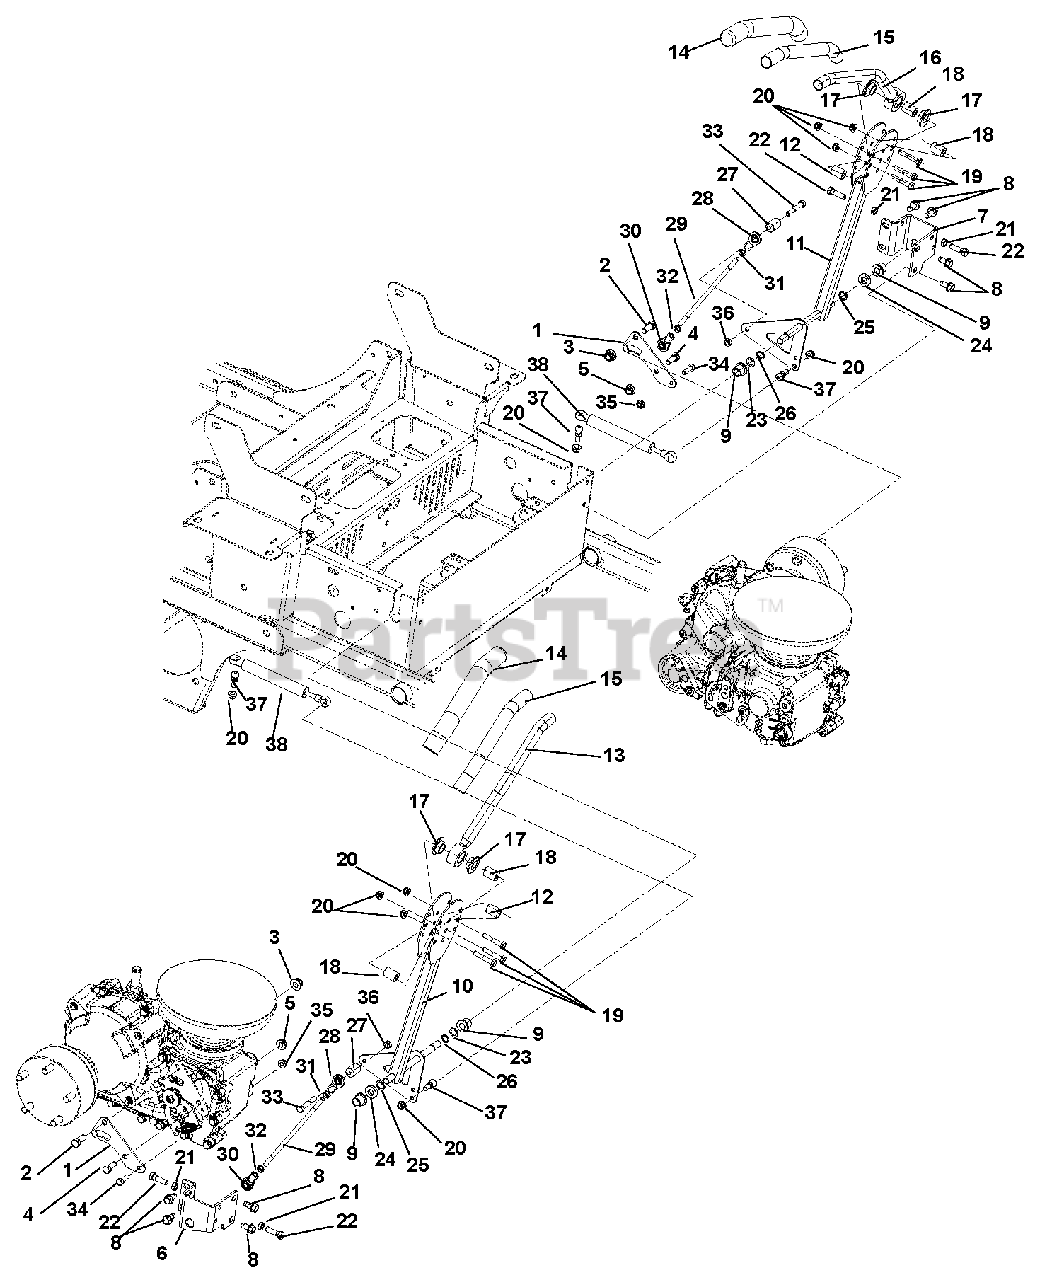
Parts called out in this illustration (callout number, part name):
1	Bracket, Control Mounting
2	Bolt, Hex .44-14 x 1.00 Grade 5
3	Nut, Locking Nylon Flange .44-14
4	Bolt, Hex .38-16 x 1.00 Grade 5
5	Nut, Locking Nylon Flange .38-16
6	Bracket, Right Hand Control Stop
7	Bracket, Left Hand Control Stop
8	Screw, Tapping .38-16 x .75 Hex Washer Head
9	Bushing, Flange .515 x .750 x .745 x 1.00 Nylon
10	Weldment, Right Hand Control Arm
11	Weldment, Left Hand Control Arm
12	Bushing, Eccentric .31 x .75 x .97
13	Handle Weldment Right Hand
14	Grip, Handlebar 1.00 x 1.38 x 11.3
15	Tube, .88ID x 1.00OD x 10.75
16	Handle Weldment Left Hand
17	Bushing, Flange .762 x 1.48 x .44 Nylon
18	Spacer .328 x .76 x 1.01
19	Bolt, Hex .31-18 x 1.75 Grade 5
20	Nut, Locking Nylon Flange .31-18
21	Nut, Hex Jam .375-16
22	Bolt, Hex .38-16 x 1.25 Grade 5
23	Washer, Flat Steel .520 x .810 x .033
24	Spacer .531 x 1.00 x .195
25	Wave Washer .531 x .781 x .125FH
26	Ring, Retaining External .500 x .050
27	Eccentric
28	Alignaball, 5/16 Right Hand Thread
29	Rod, Steering
30	Alignaball, 5/16 Left Hand Thread
31	Nut, Jam .31-24
32	Nut, Jam Left Hand .31-24
33	Bolt, Hex .31-18 x 2.00 Grade 5
34	Bolt, Hex .31-18 x 1.00 Grade 5
35	Nut, Locking Top Flange .31-18
36	Nut, Locking Center .31-18
37	Stud, Ball
38	Damper
